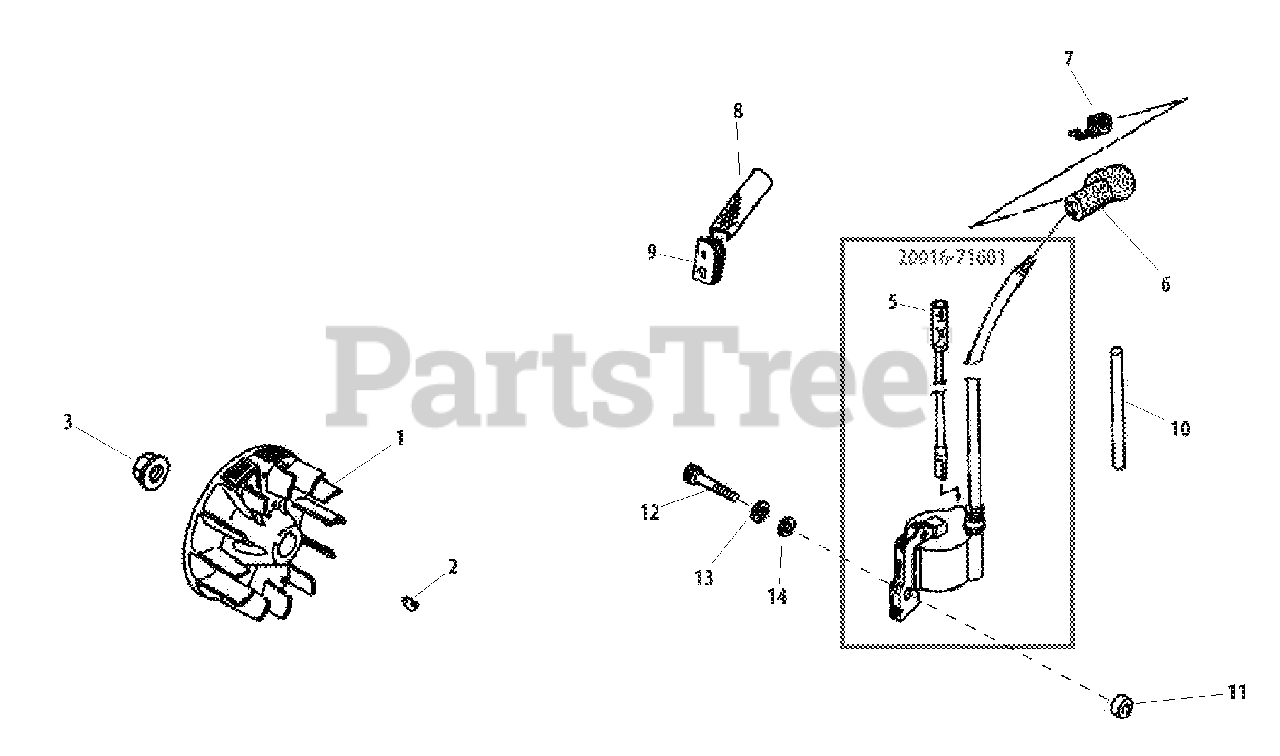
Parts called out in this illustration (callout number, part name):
1	FLYWHEEL
2	KEY - 3X10
3	NUT - 8
5	LEAD - IGNITION
6	CAP, SPARK PLUG
7	TERMINAL, SPARK PLUG CAP
8	TUBE
9	GROMMET
10	TUBE
11	INSULATOR
12	SCREW - 4X26
13	LOCKWASHER - 4
14	WASHER - 4
